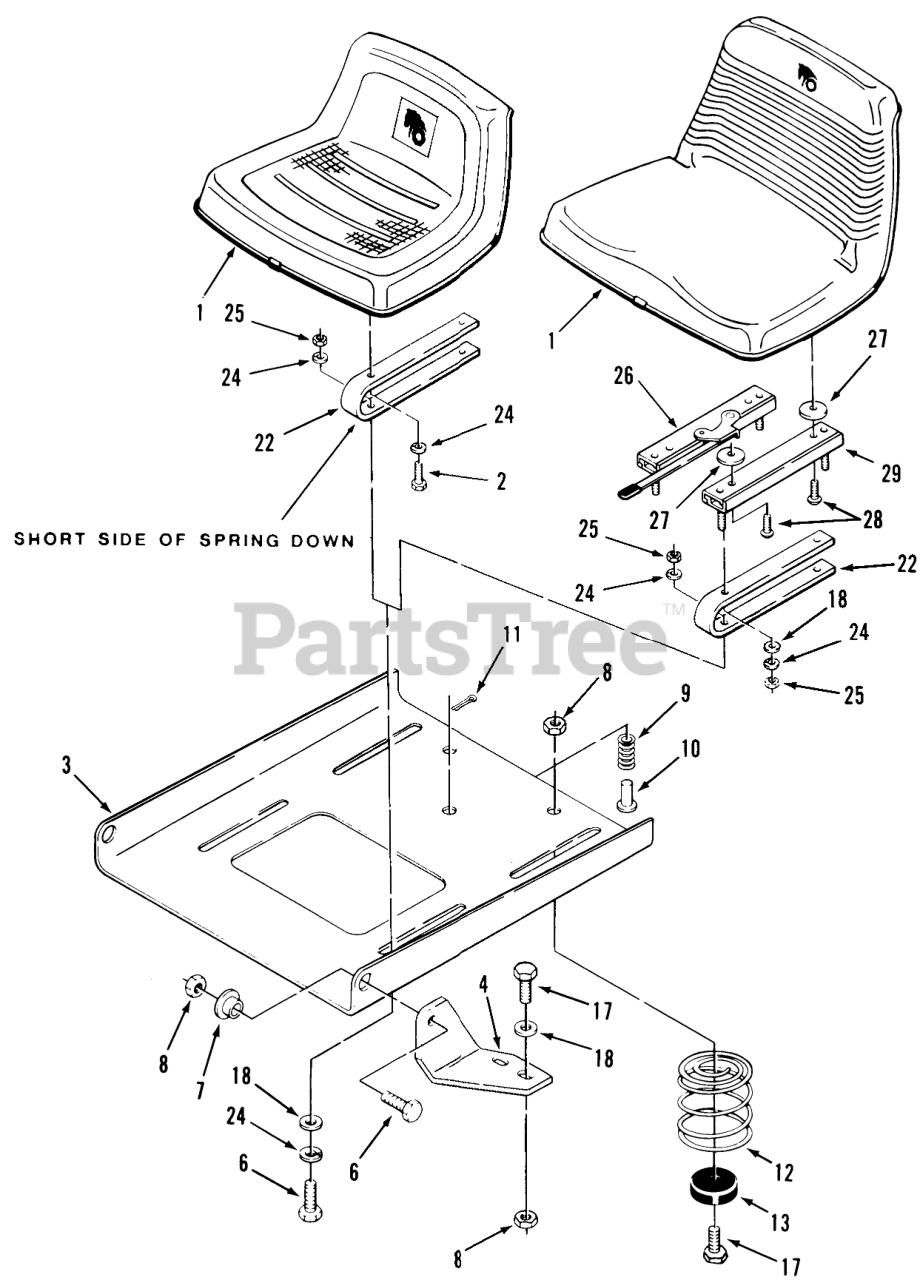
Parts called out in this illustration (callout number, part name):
1	Seat
2	Bolt
3	PLATE-SEAT PIVOT B
4	BRACKET-PIVOT L.H B
4	Bracket-Pivot RH
6	HHCS
7	BUSHING
8	Nut
9	SPRING-SEAT SWITCH
11	Cotter Pin
12	SPRING
12	SPRING-SEAT NYLON
13	BUMPER
17	Bolt
18	WASHER 5/16 SAE
22	Seat Spring
24	Lockwasher
25	Nut
26	Adjuster-Seat
27	SPACER-NYLON
28	Screw
29	ADJUSTER-R.H. SEAT
